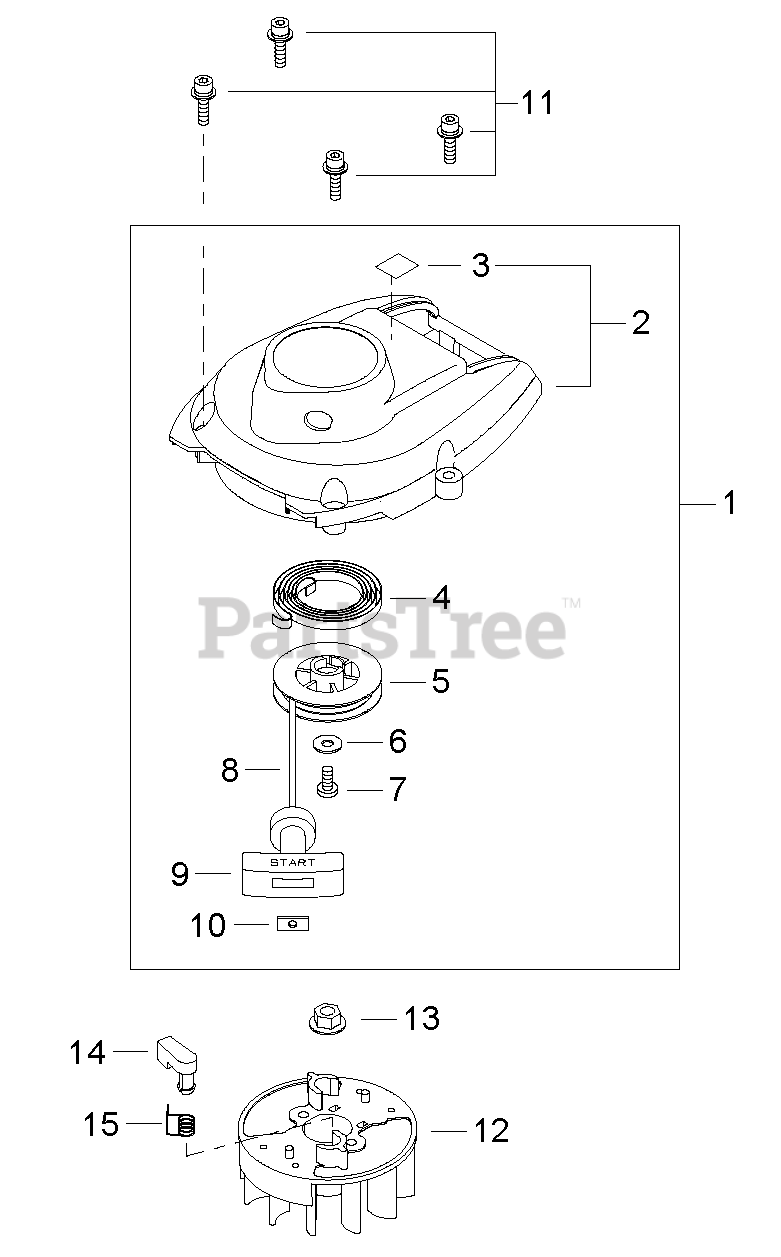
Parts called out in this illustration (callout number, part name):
1	STARTER ASSY, RECOIL
2	CASE ASSY, RECOIL STARTER
3	LABEL, CAUTION - HOT
4	SPRING, RECOIL
5	REEL, ROPE
6	WASHER 5
7	SCREW 5
8	ROPE, STARTER
9	GRIP, STARTER
10	RETAINER, ROPE
11	BOLT, ADHESIVE M5×20
12	FLYWHEEL
15	SPRING, TORSION
